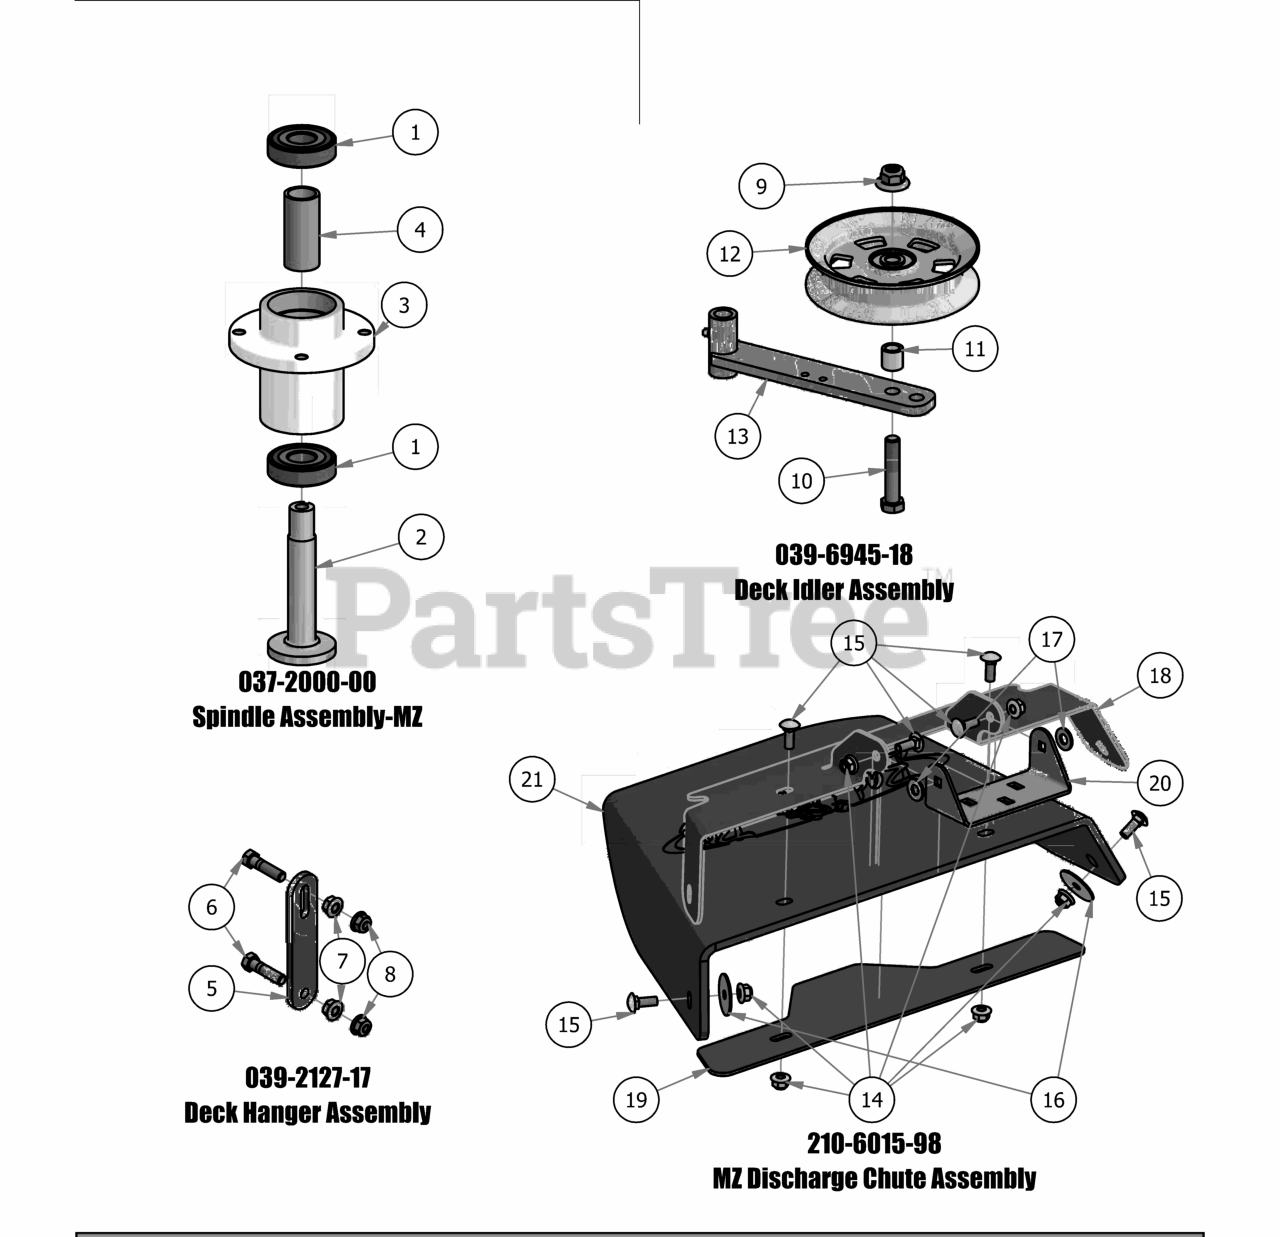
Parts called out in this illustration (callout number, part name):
1	Spindle Bearing
2	Spindle Shaft
3	Spindle Housing
4	Spindle Spacer-Component
5	2017 MZ/ZT Deck Hanger
6	3/8" x 1 1/2" Hex Bolt
7	3/8" Flange Nut
8	3/8" Nylock Flange Nut
9	1/2-13 Nylon Flange Nut
10	1/2" x 2 1/2" Hex Bolt
11	Spacer 3/4 OD x 1/2 ID x 3\4 Length
12	5" Idler Pully
13	Deck Idler
14	5/16" Nylon Flange Nut
15	5/16" x 7/8" Carriage Bolt
16	5/16 Fender Washer
17	.360 ID Plastic Washer
18	Discharge Chute Bracket 48 MZ (Upper)
19	2017 MZ Discharge Chute Bracket-Lower
20	Chute Hanger 48 MZ
